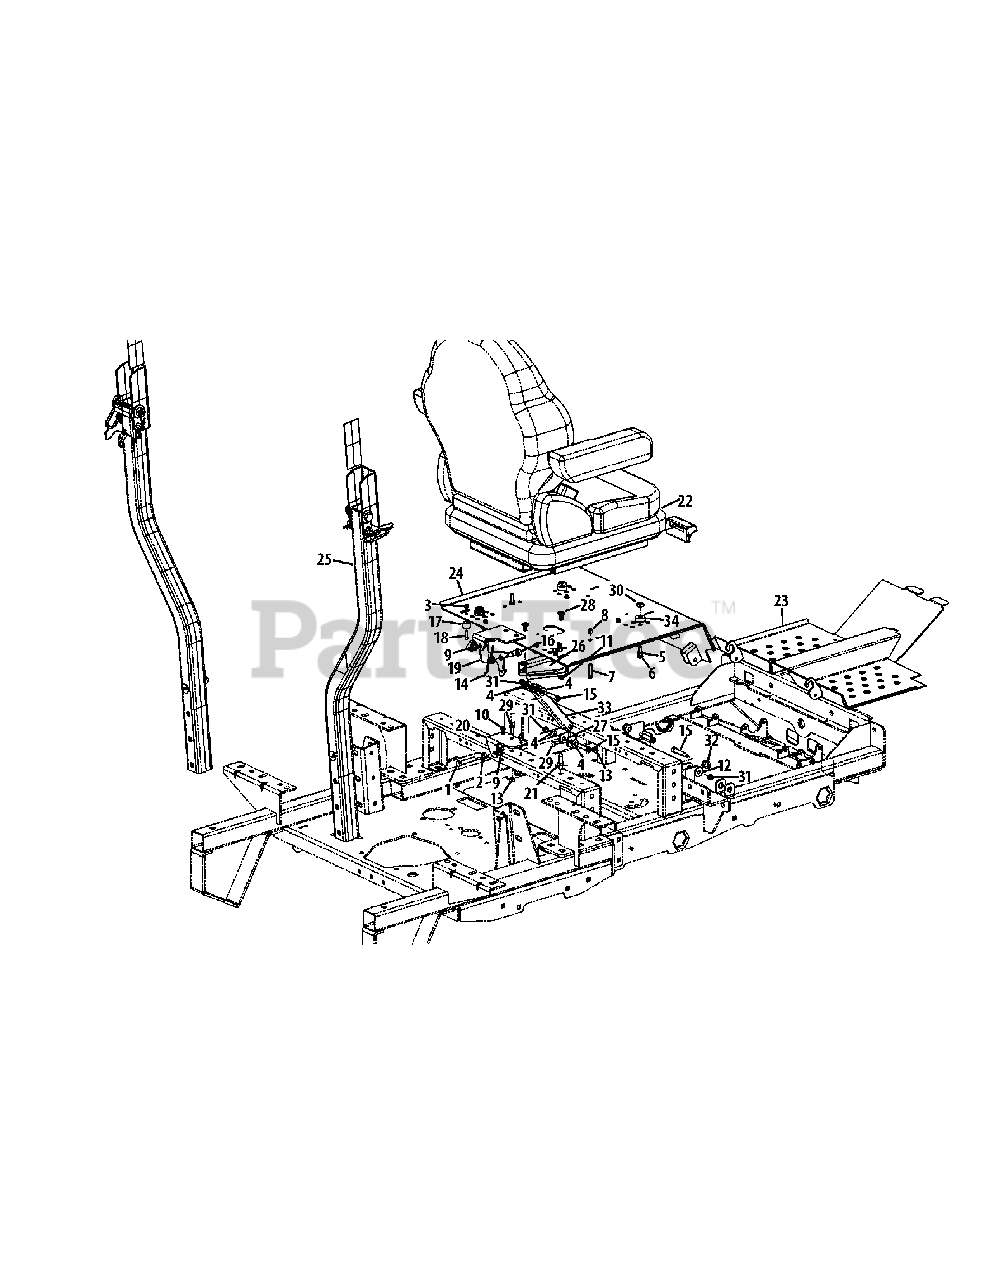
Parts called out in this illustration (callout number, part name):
1	Hex Screw, 3/8-16 x 2.00
2	Nut, 3/8-16
3	Nylock Nut, #10-24
4	Wsdher, .406 x .813 x .063
5	Lock Washer, .312 x .583 x .083
6	Hex Screw, 5/16-18 x 1.00
7	Hex Screw, 5/16-18 x 1.25
8	Flange Lock Nut, 5/16-18
9	Flange Counter Lock Nut, 3/8-16
10	Hex Screw, 1/4-20 x .500
11	Flange Counter Lock Nut, 5/16-18
12	Washer, .406 x 1.00 x .105
13	Flange Top Lock Nut, 1/4-20
14	LH Torsion Spring, .725 x 1.07 x .09
15	Shoulder Bolt, 5/16-18 x .37 x 1.50
16	Shoulder Bolt, 3/8-16 x .50 x .75
17	Bump Stop w/ Washer
18	Flat Head Screw, #10-24 x .750
19	Lever Latch Bracket
20	Mount Latch Bracket
21	Center Adjust Stud, .375 x 1.125
22	Suspension Seat w/ Seat Belt
22	Seat Back Cover
22	Seat Bottom Cover
22	Armrest Kit
22	Seat Switch Assembly
23	Wide Assembly Floor Panel
24	Seat Mount Bracket Assembly
25	Folding ROPS Assembly
26	Seat Support Lock Bracket
27	Seat Link Pivot Mount Bracket
28	Carriage Bolt, 5/16-18 x .62
29	Hex Screw, 1/4-20 x .75
31	Hex Lock Nut, 5/16-18
32	Grommet, .38 x .75 x .75
34	Spacer, .406 x 1.00 x .38
